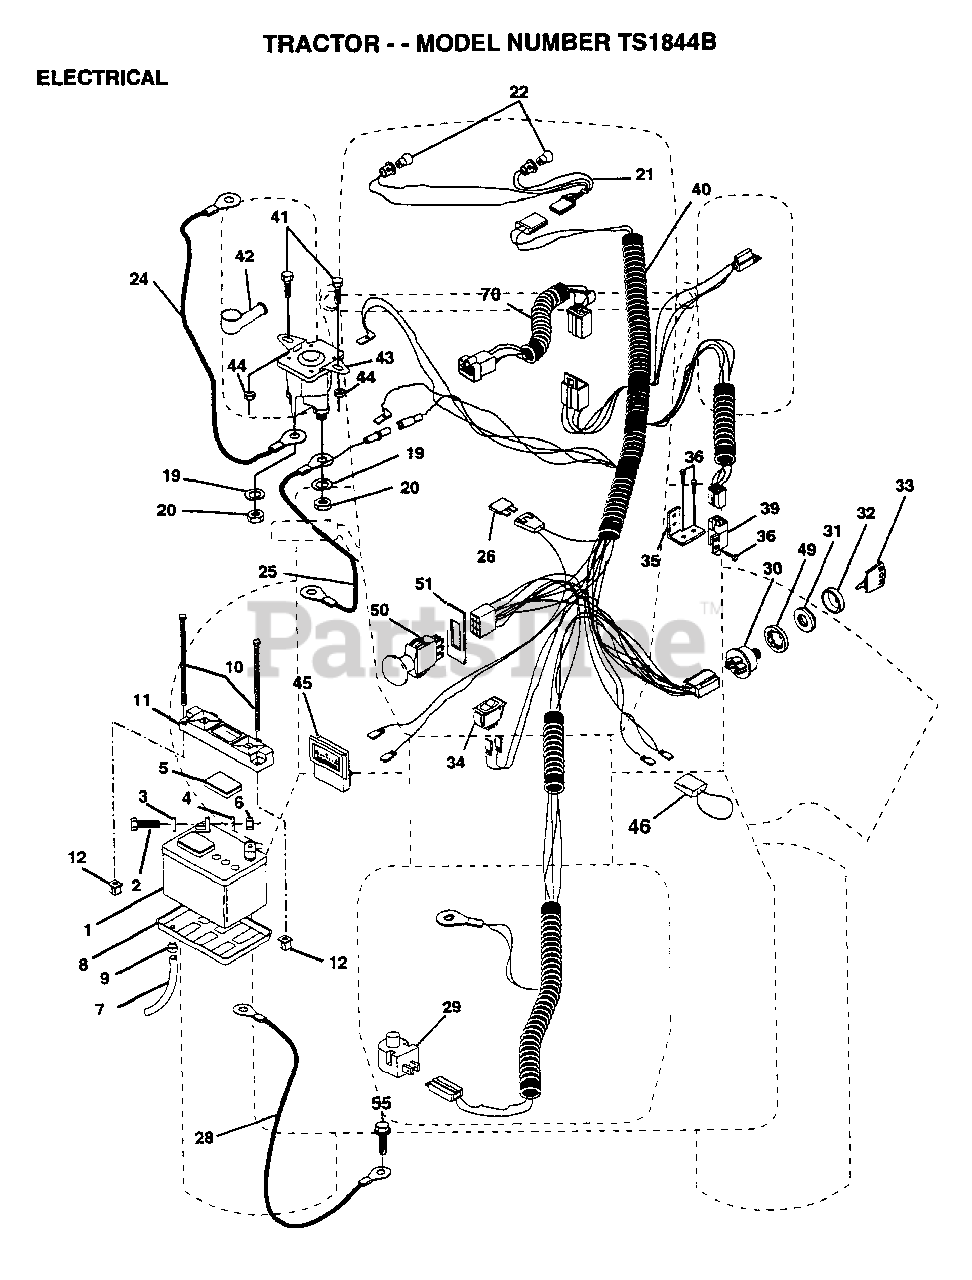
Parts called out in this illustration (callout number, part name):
2	BOLT LT
3	WASHER
4	LOCKWASHER
5	"CAP,BATTERY "
7	"DRAIN TU T, BATT"
8	"TRAY T, BATTERY"
9	HOSE CLAMP T
20	NUT
21	"HARNESS,LIGHT SOC"
22	HEADLAMP BULB
24	CABLE-BATTERY T
25	CABLE.6GA.22W/16W
26	FUSE HYT
28	CABLE.GRND.6GA.21
29	SWITCH SEAT
32	COVER KEY SWITCH
33	KEY MLD GEN DELTA
34	SWITCH LT
35	BRACKET LT
36	SCREW
39	SWITCH INTERLOCKT
40	HARNESS.ING.ELEC.
41	BOLT.HX.1/4-20
44	NUT
45	AMMETER
46	PROTECTION LOOP
49	LOCKWASHER
51	RING RETAIN PTO
55	SCREW LT
70	HARNESS.ENG.CV-18
